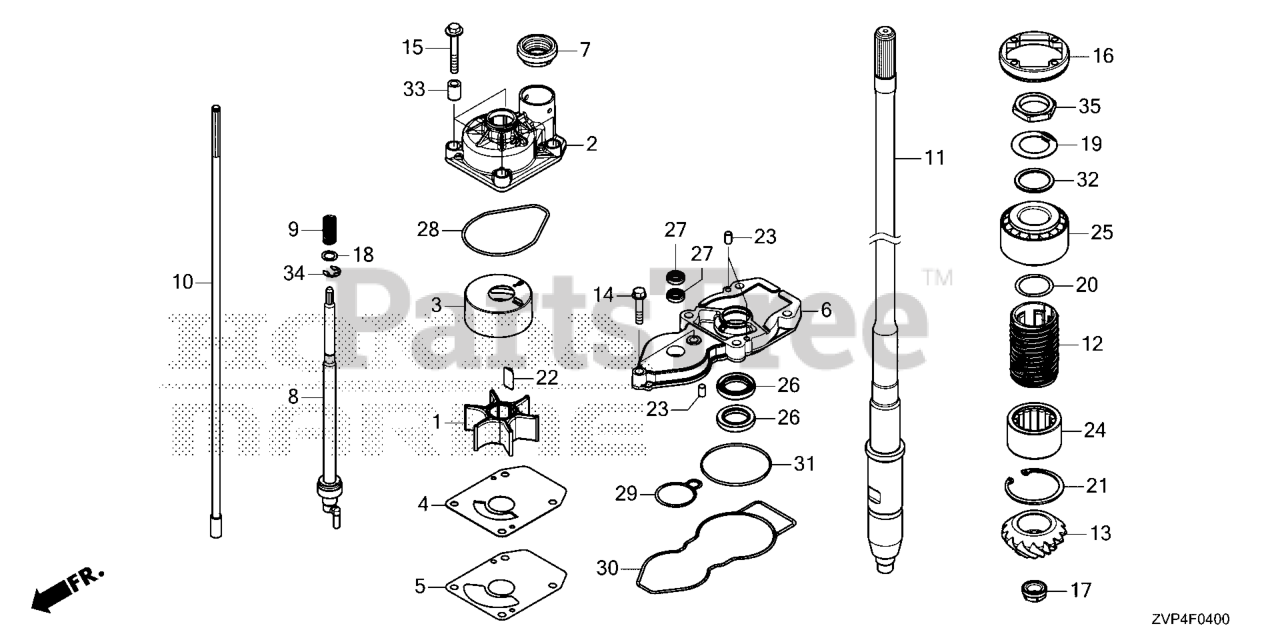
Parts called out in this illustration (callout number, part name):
1	IMPELLER, PUMP
2	HSG, IMPELLER
3	LINER, WATER PUMP
4	COVER, IMPELLER
5	GASKET B, IMPELLER
6	HSG, WATER PUMP
8	ROD, SHIFT
9	SPG, SHIFT ROD
10	ROD A, SHIFT (XXL)
11	SHAFT, VERTICAL UL
12	SLINGER, OIL
13	GEAR, PINION
14	BOLT, FLANGE (8X38)
15	BOLT-WASHER (8X60)
16	NUT, LOCK (82MM)
17	NUT, HEX. (18MM)
18	WASHER, PLAIN (12MM)
19	WASHER, TAPER ROLLER
20	SHIM A, GEAR
20	SHIM B, GEAR
20	SHIM C, GEAR
20	SHIM D, GEAR
21	CIRCLIP, IN (65)
22	KEY, WOODRUFF
23	PIN, DOWEL (6X10)
24	BRG (40X64X37)
25	BRG (35X80X51)
26	SEAL, WATER (30X45X7)
27	SEAL, WATER (12X21X6)
28	O-RING, WATER PUMP
29	O-RING, SHIFT ROD
30	O-RING, HSG PUMP
31	O-RING (79.4X2.4)
33	COLLAR, DISTANCE
34	E-RING (10MM)
35	NUT, HEX. L (35MM)
